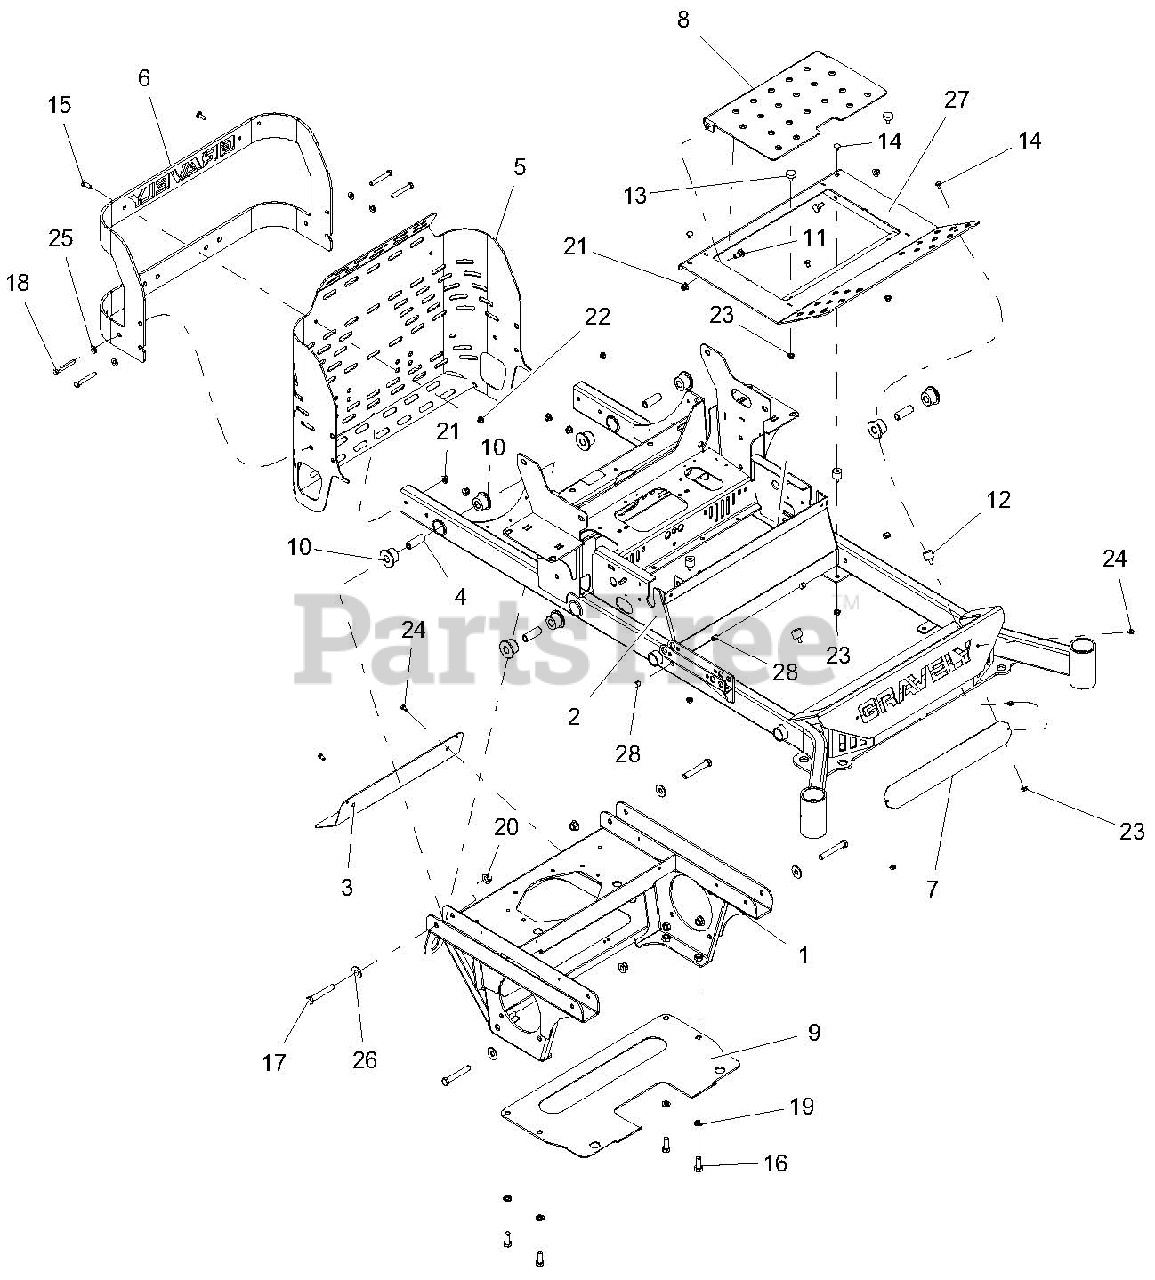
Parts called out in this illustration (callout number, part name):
1	WLDT, 200 PT AXLE/ENGINE FRAME
2	52-66" MAIN FRAME W/SAFETY DECALS
3	SHIELD, MUFFLER HEAT
4	SPCR, .50 X .75 X 2.23 YZ
5	WLDMT, PT200 REAR BUMPER
6	REAR BUMPER W/SAFETY DECALS-GAS
7	PLATE, BUMPER LOGO BACKING-BLACK
8	PANEL, INSPECTION
9	PLATE-TRANSMISSION SKID-RED
10	BSHG, FLANGE .750 X 1.510 X 1.130 X 2.000
11	BLT, SHLDR EP .38-16X.30 HEX YZ
12	BUMPER, STUD MOUNTED W/FEMALE INSERT
13	BUMPER, RUBBER
14	BLT-RDHDSQNK .31-18X.50 G5 YWZC
15	BLT-RDHDSQSHNK .31-18X1.00 G5YWZC
16	BLT-HEX .50-13X1.25 GR5 YWZC
17	BLT-HEX .50-13X3.50 GR5 YWZC
18	BLT-HEX .38-16X2.75 GR5 YWZC
19	WSHR-LK .50X.125 REG YWZC
20	NUT-LK-NYL-FLG .50-13 YWZC
21	NUT-LK-NYL-FLG .38-16 YWZC
22	NUT-LK-NYL-FLG .31-18 YWZC
23	@NUT-SPNLK-FLG .312-18 YWZC
24	SCR-TAP .25-20X.50 HWH TR YWZ
25	WSHR-FL-STL.406X.812X.065 YWZ
26	WSHR-FL-STL.563X1.38X.109YWZC
27	FOOTPLATE WLDMT W/SAFETY DECAL
28	PLUG, HOLE .500
